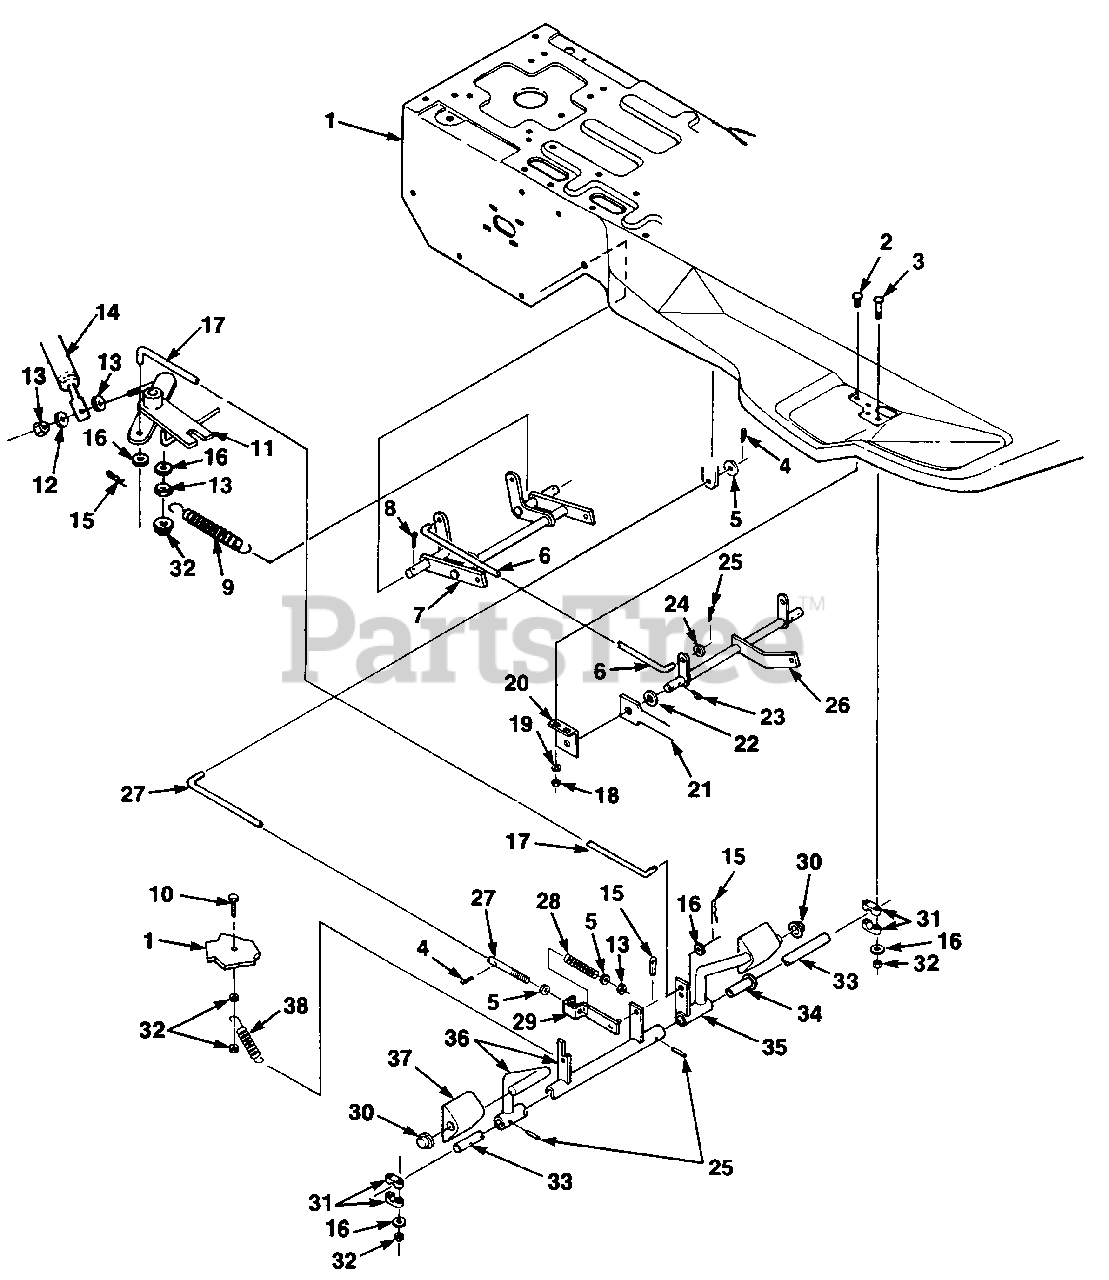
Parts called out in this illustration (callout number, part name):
2	BOLT- Carr. 1/4-20 x 5/8
3	BOLT- 1/4-20 x 1 1/2
4	PIN- Cotter
5	WASHER- 5/16 Plain
6	ROD- Deck lift
7	BRACKET- Rear hanger
8	PIN- Cotter
9	SPRING- Extension
10	SCREW- 1/4-20 x.625
11	ARM- Pivot
12	WASHER 5/16
13	NUT- Hex 5/16-18
15	PIN- Cotter
16	WASHER- 1/4"
17	ROD- Clutch
18	NUT- 1/4-20
19	WASHER- Lock 1/4
21	SUPPORT- Front axle
22	WASHER- Flat 7/16
23	PIN- Cotter
24	WASHER- Flat 7/16
25	PIN- Cotter
26	HANGER- Front
27	ROD- Brake
28	SPRING- Brake
29	BRACKET- Brake spring
30	NUT- Push 5/8
32	NUT- Centerlock hex 1/4-20
33	PEDAL SHAFT
35	PEDAL- Clutch
36	PEDAL- Brake
37	PEDAL- Rubber
